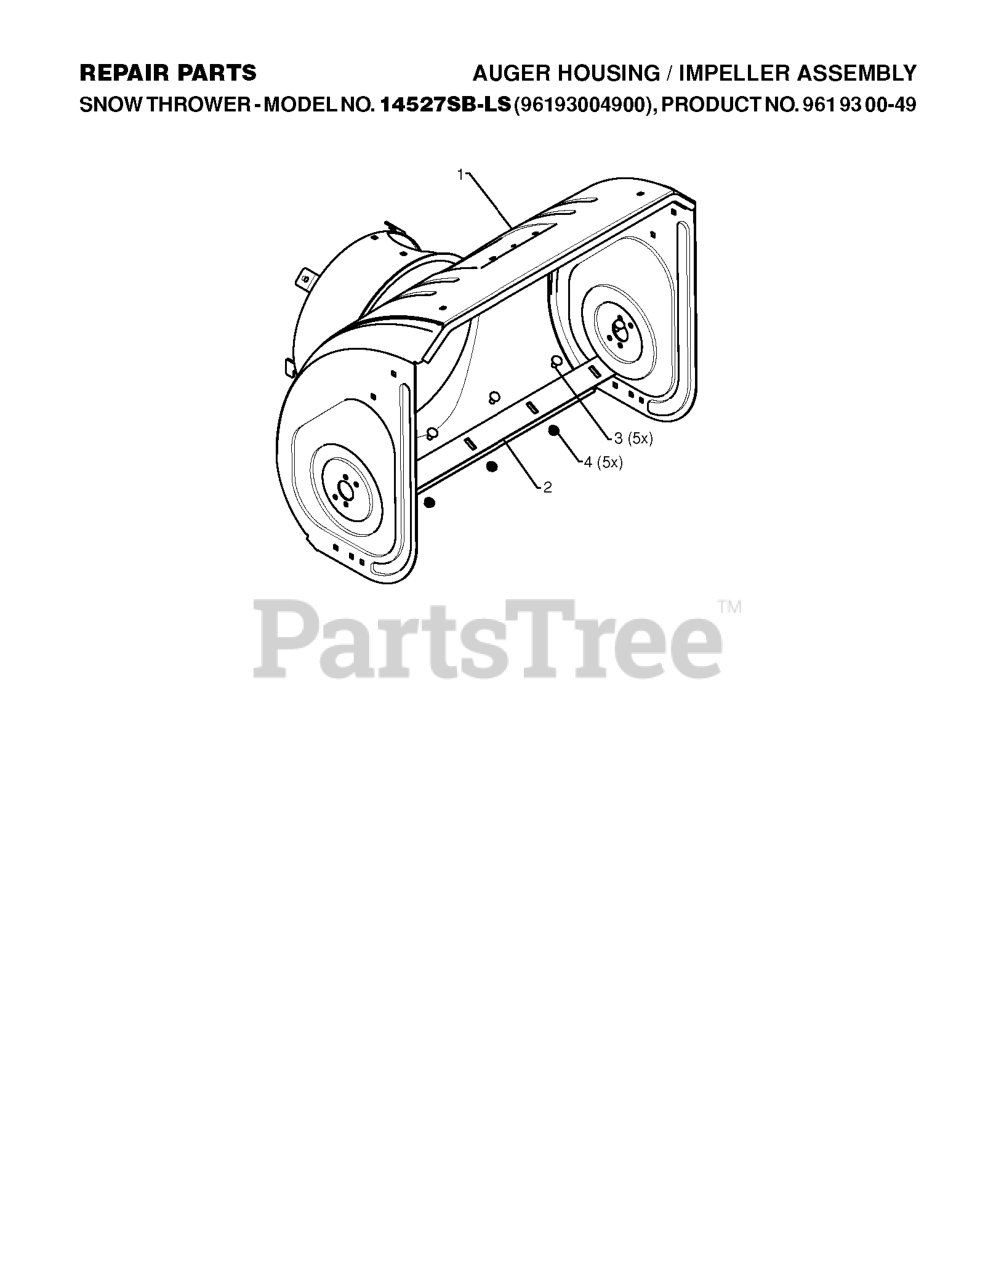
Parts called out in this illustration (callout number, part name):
1	HOUSING, AUGER
2	RP BAR.SCRAPER.27.PNT.431
3	BOLT
4	NUT.FLANGE.5/16
